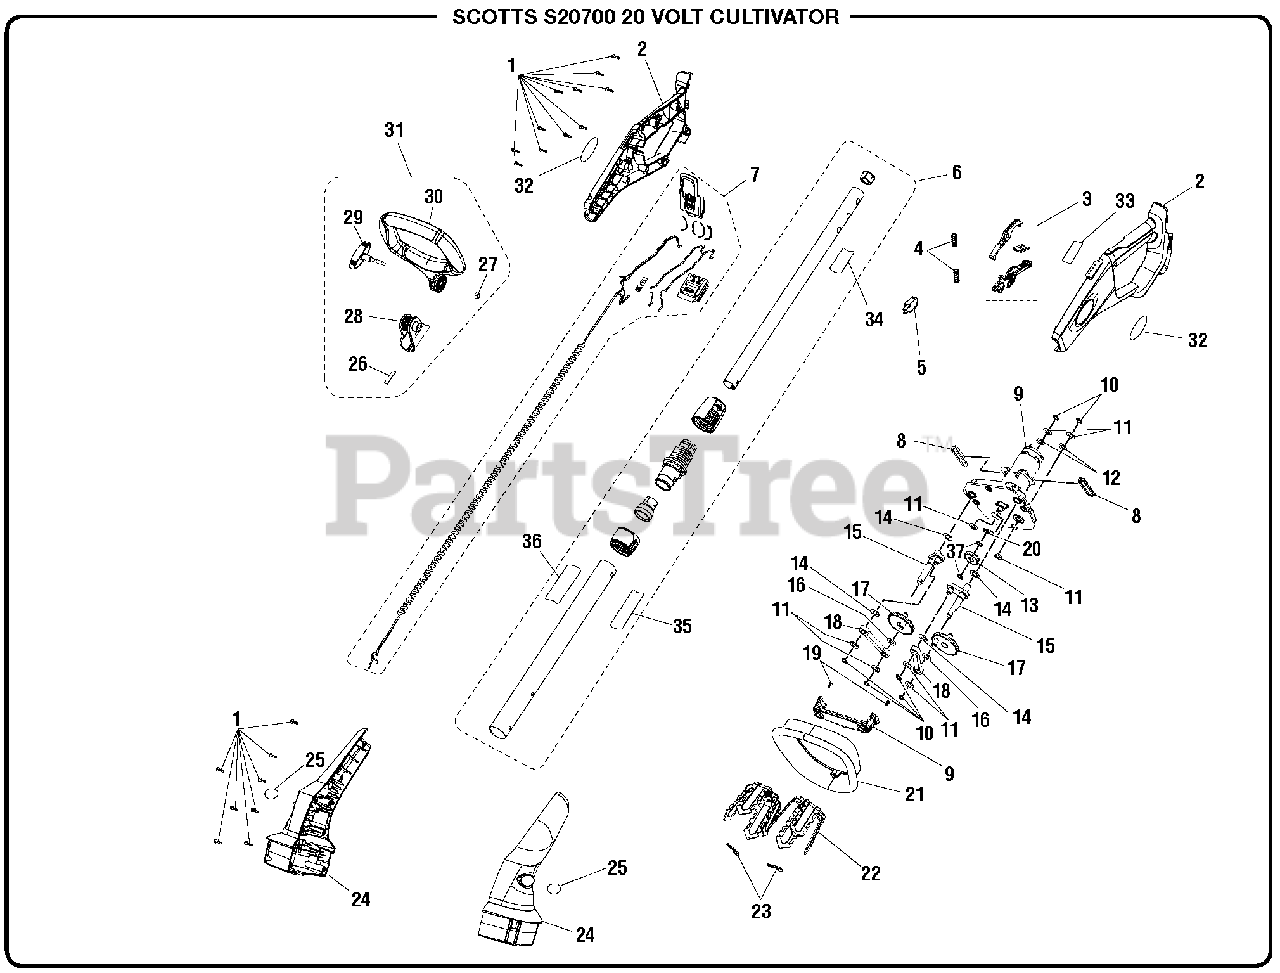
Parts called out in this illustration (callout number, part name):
1	Screw (M4 x 14 mm,T15 Torx Pan Hd.)
2	Handle Assembly
3	Switch Trigger and Lock-Out Lever Assembly
4	Compression Spring
6	Pole Assembly
7	Wiring Harness
8	Rubber Isolator
9	Motor and Clutch Assembly
10	Retaining Ring
11	Washer (ID8 x OD14 x 0.5t)
12	Wavy Washer (ID8.5 x OD12.5 x 2t)
13	Clutch Gear
14	Washer (ID10 x OD17.5 x 0.5t)
15	Pivot Arm Assembly
16	Washer (ID8 x OD16 x 1t)
17	Drive Gear Assmebly
18	Connect Rod
19	Screw (M3 x 8 mm, Pan Hd.)
20	C-Ring (Retaining Ring)
23	Hitch Pin
24	Housing Assembly
25	Motor Housing Label
26	Rubber Plate
27	Hex Nut (M6)
28	Handle Bracket Assembly
29	Auxillary Hanlde Knob
30	Front Handle
31	Auxillary Handle Assembly
32	Handle Label
33	Fuel Gauge Label
34	Data Label
35	Warning Icon Label
36	Warning Transition Label
37	Retaining Ring
